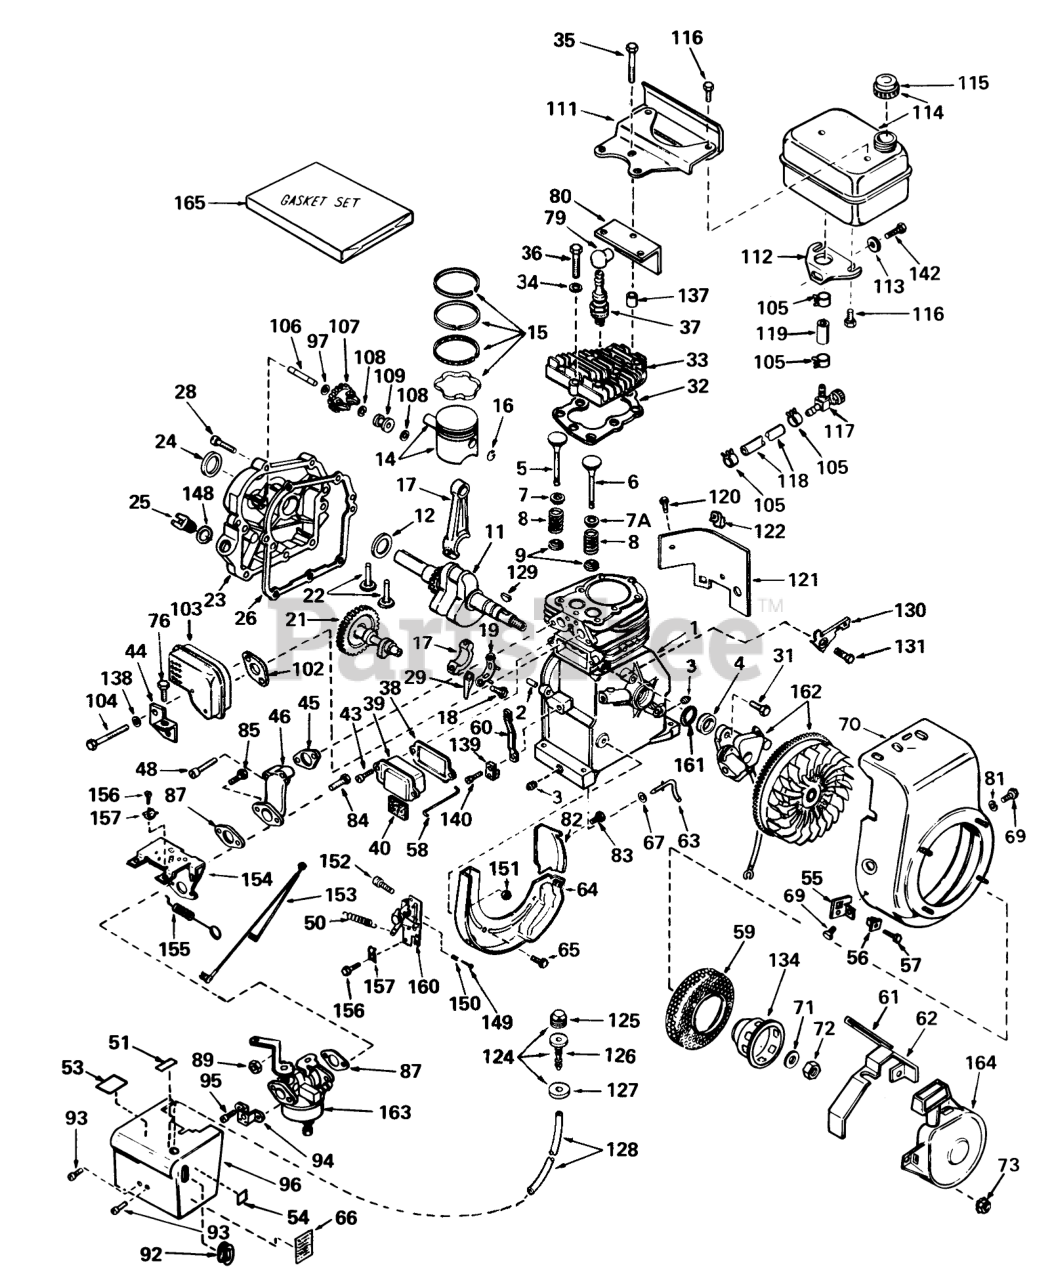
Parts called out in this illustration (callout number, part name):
1	Cylinder Assy. (Incl. Nos.2, 3 & 4)
2	Pin-Dowel
3	Plug-Drain, Oil (SQH 1/4-18)
4	Seal-Oil
5	Valve, Intake (Std.) (Incl. Nos. 7, 8 & 9)
5	Valve, Intake (1/32" oversize) (Incl. Nos. 7, 8 & 9)
6	Valve, Exhaust (Std.) (Incl. Nos. 7A, 8 & 9)
6	Valve, Exhaust (1/32" oversize) (Incl. Nos. 7A, 8 & 9)
7	Cap-Upper Valve Spring
7A	Cap, Upper Valve Spg (Exhaust)
8	Spring-Valve
9	Cap-Valve, Spring
11	Crankshaft Assy.
12	Washer-Thrust
14	Piston & Pin Assy. (Incl. 2 of No. 16) (Std.)
14	Piston & Pin Assy. (Incl. 2 of No. 16) (.010 oversize)
14	Piston & Pin Assy. (Incl. 2 of No. 16) (.020 oversize)
15	Ring Set-Piston Std.
15	Ring Set-Piston .010 oversize
15	Ring Set-Piston .020 oversize
16	Ring-Retaining, Piston Pin
17	Rod Assy., Connecting (Incl. Nos. 18,19 & 29)
18	Connecting Rod Bolt
19	Plate Lock
21	Camshaft
22	Lifter-Valve
23	Cover, Cylinder (Incl. Nos. 24, 25, 106 & 148)
24	Seal-Oil
25	Plug, Oil filler (Incl. No.148)
26	Gasket-Cylinder Cover
28	Screw
29	Dipper-Oil
32	Oil Fill Tube
33	Head Cylinder
35	Screw Hex Hd. Cap
36	Screw
37	Plug, Spark (Champion RCJ8 or Autolite AR7N Resistor type)
38	Gasket Breather
39	Breather Assy. (Incl. Nos. 38 & 40)
40	Element-Breather
44	Bracket-Cover, Carburetor
45	Gasket-Intake
46	Pipe-Intake
48	Screw (1/4-20 x 1-19/32)
50	Spring-Extension
51	Decal-Primer
53	Decal, Warning
54	Decal, "Choke"
55	Bracket
56	Grommet
57	Screw
58	Link-Governor to Throttle
59	Screen-Starter
60	Lever, Governor
61	Seal, Snowguard
62	Guard-Starter
63	Rod-Governor
64	Baffle-Blower Housing
65	Screw (1/4-20x19/32)
66	Decal, Instruction
67	Washer-Flat
69	Screw
70	Housing, Blower
71	Washer-Spring
72	Hex Nut
73	Nut and Lock Washer (1/4-28)
76	Screw (10-24 x 3/8)
79	Cover-Spark Plug
80	Baffle-Heat
82	Baffle-Extension
83	Screw-Hex Washer Hd.
84	Screw
85	Screw-Fil. Hd.
87	Gasket
89	Nut and Lock Washer (1/4-28)
92	Grommet, Carburetor cover
93	Screw (8-32 X 5/16)
94	Bracket-Choke
95	Screw (10-32 x 1/2)
96	Cover, Carburetor
97	Washer-Flat
102	Gasket-Exhaust
103	Muffler
104	Screw-Fil. Hd.
105	Clamp-Line, Fuel
106	Shaft-Governor
107	Gear Assy., Governor (Incl. No. 97)
108	Ring-Retaining
109	Spool-Governor
111	Plate-Fuel Tank
112	Bracket, Fuel Tank Lower
114	Tank Assy., Fuel (Incl. Nos. 115 & 116)
115	Cap, Fuel
116	Screw (1/4-15x7/8)
117	Valve-Shut Off
118	Line-Fuel
119	Line-Fuel (8.62)
121	Extension-Blower
122	51004 GIL ROTARY TI
124	Primer Assy. (Incl. Nos. 125, 126 & 127)
125	33164A GILO"HITCH A
126	Body Primer
127	Retainer, Primer Bulb
128	Line, Primer
129	Key, FIywheel
130	Bracket-Hold Down
131	Screw, Hex Hd. w/Conical
134	Cup, Starter
139	Clamp-Lever, Governor
140	Screw
142	Screw (1/4-20 X 5/8)
148	Gasket
149	Screw
150	Spring-Compression
151	Nut-Lock
152	Screw
153	Wire, Ground
154	Bracket, Speed Control
155	51011/13 TILL.O/P'7
156	Screw (10-32 x 3/8)
157	Conduit
160	Bracket Assy., Control (Incl. Nos. 149, 150, 151 & 152)
161	Gasket Stator
163	Carburetor (Incl. 1 of No. 87)
164	Starter Assy., Rewind
165	Gasket Set
